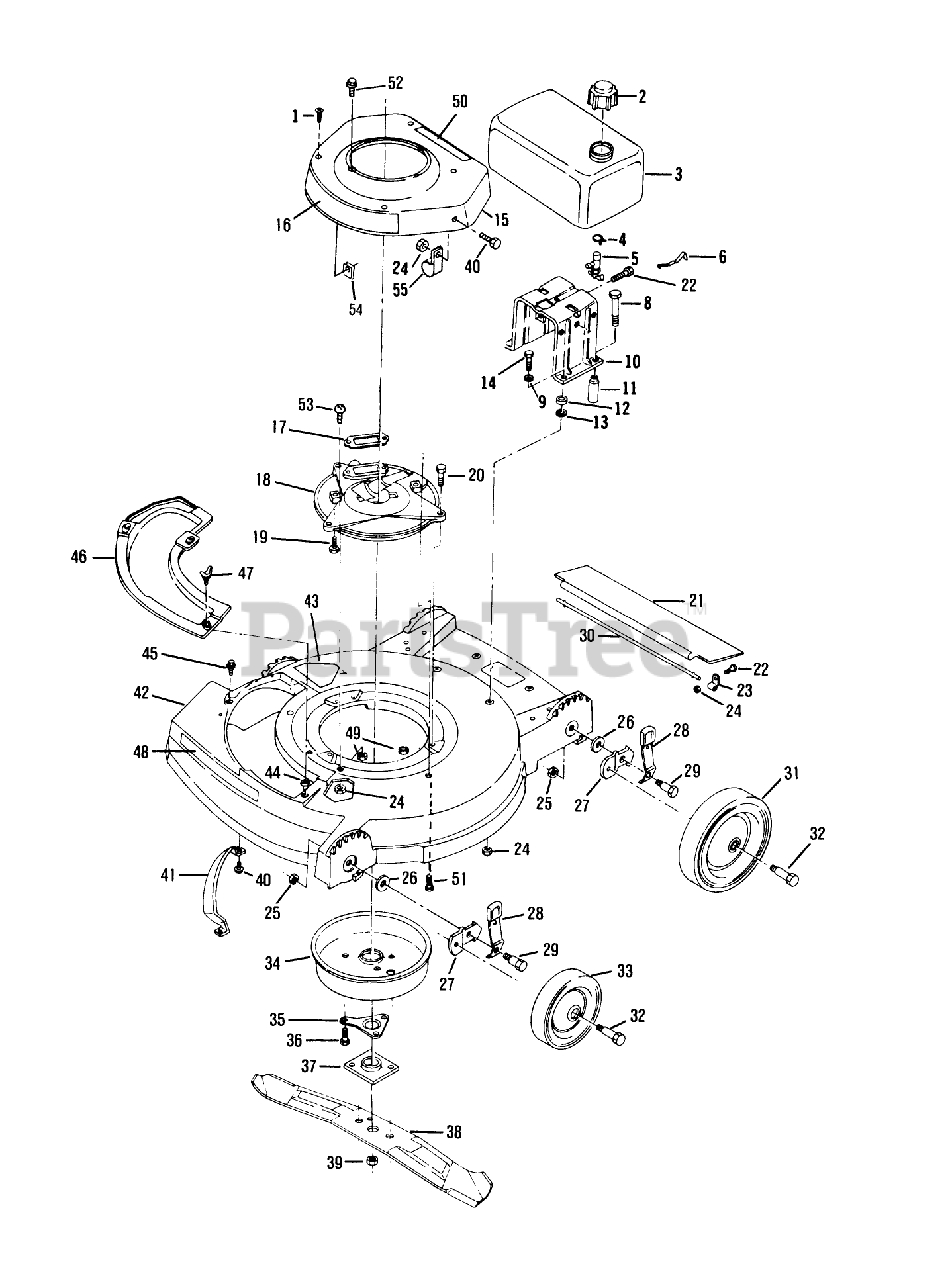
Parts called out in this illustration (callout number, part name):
1	SCREW - SELF TAPPING
2	FUEL CAP & INSERT
3	TANK - FUEL
4	CLAMP - HOSE S
5	VALVE&SCREEN SM
6	SPRING
9	WASHER
13	WASHER
14	BOLT PIONEER
18	PLATE F
19	SCREW V
20	SCREW-HH
21	T/SHIELD GEAUGA
23	CLAMP ROD KMC
24	LOCKNUT E
26	WASHER
28	SPRING ARM ASM
29	BOLT
30	ROD 21" ADVANCE
32	BOLT-SHOULDER
33	WHEEL & TIRE
34	MUFFLER COVER F
35	SUPPORT F
36	SCREW
37	PLATE AND COLLAR ASM
39	NUT-BLADE
41	BAR-TOE
47	WING SCREW LAWRE
49	NUT-LOCK F
52	SCREW SEMS SM
54	PUSHNUT F
